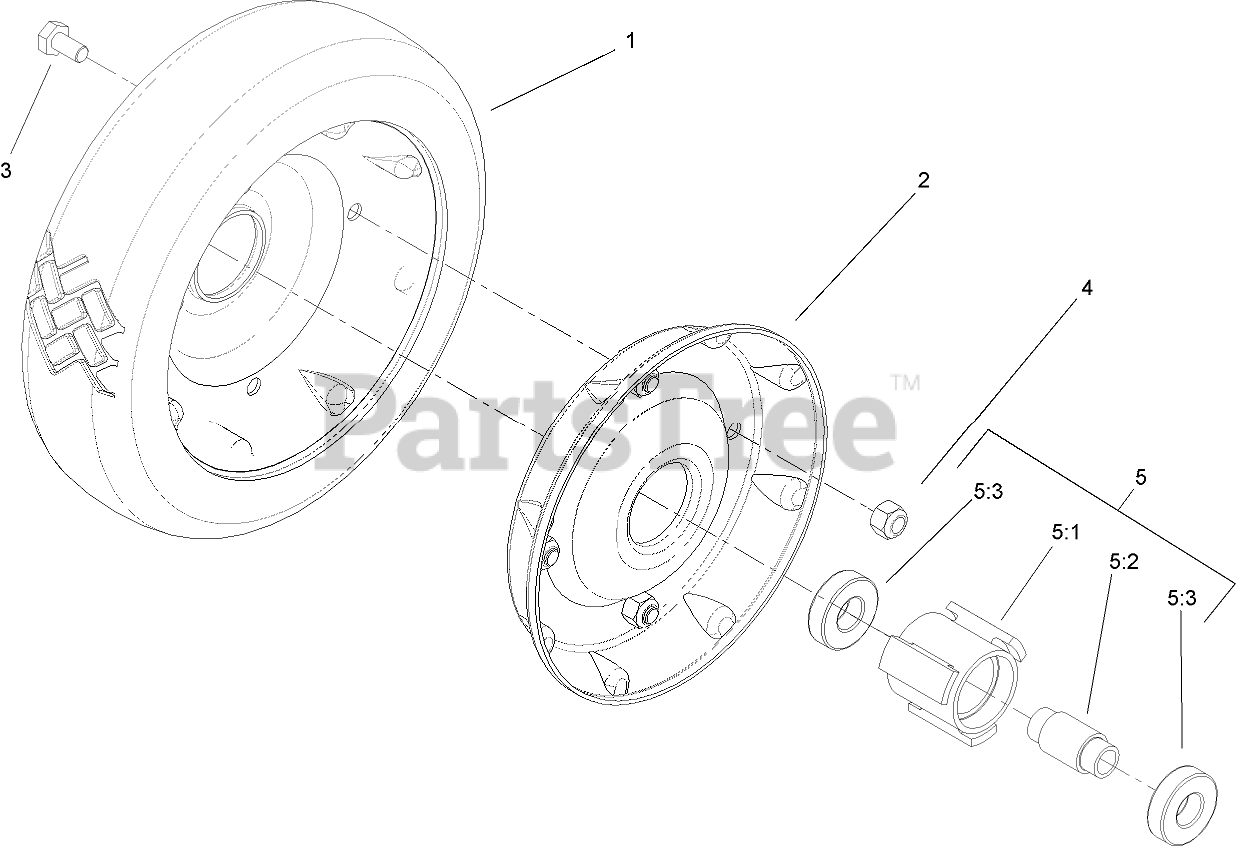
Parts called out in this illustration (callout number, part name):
2	PLATE-WHEEL, HALF
3	SCREW-HH
4	NUT-LOCK, NI
5	HUB and BEARING ASM
5:1	HUB-BEARING
5:2	SPACER-BEARING
5:3	BEARING-WHEEL
